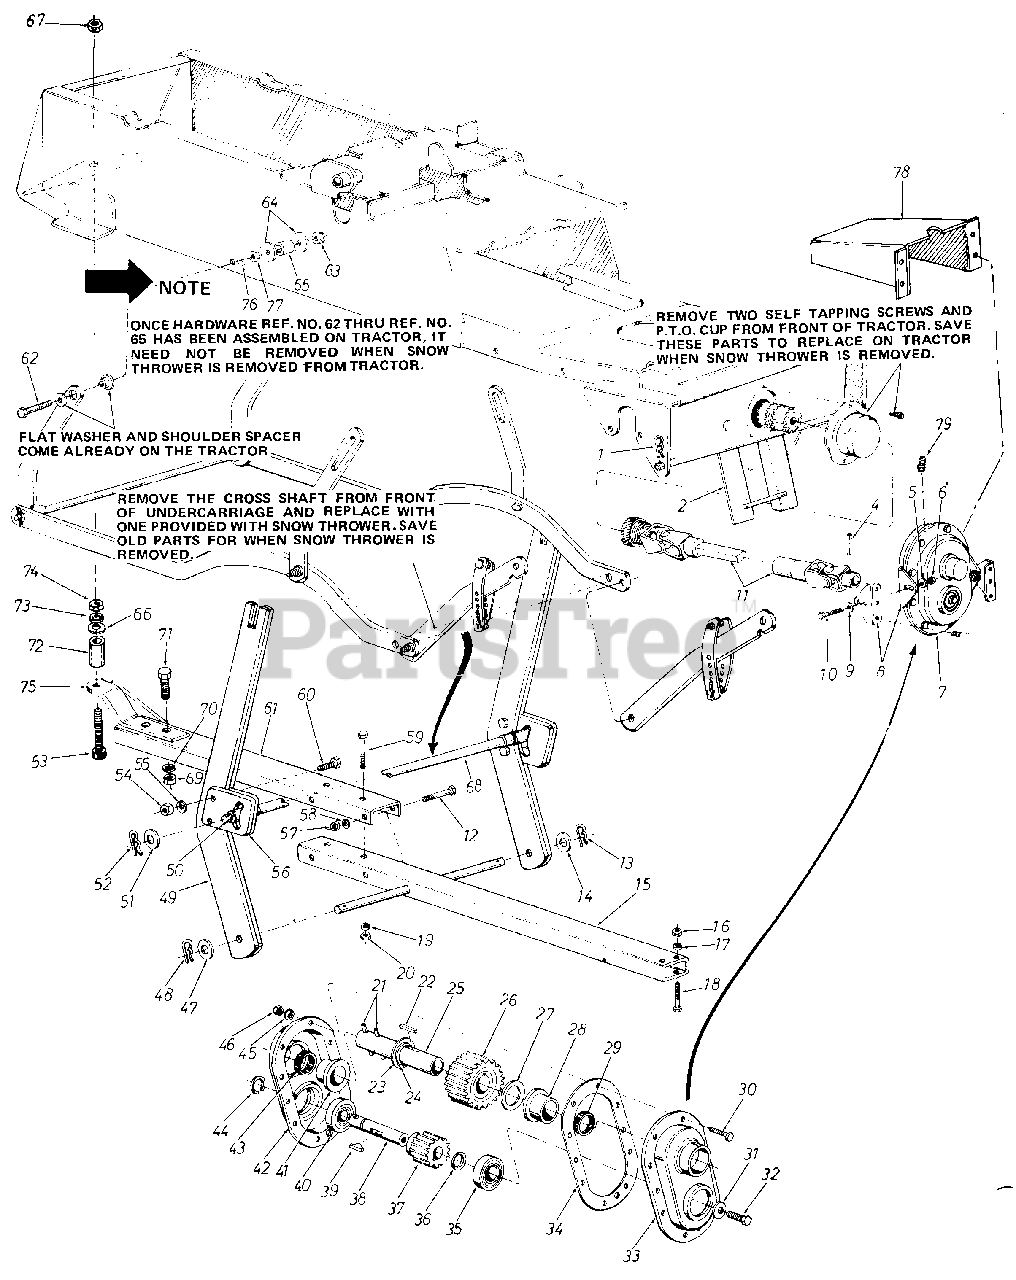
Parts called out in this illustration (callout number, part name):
1	Intern. Cotter Pin 3/4" Dia.
2	Guide Bracket Ass'y.
4	Spring Pin Spirol 1/4" Dia. x Lg.
5	BellevilleWash. .341" I.D. x .88" O.D.
6	Hex Nut 5/16-18 Thd.*
7	Gear Box Ass'y. Comp.
8	Gear Box Support Brk't.
9	Belleville Wash. .341" I.D. x .88" O.D.
10	Hex Scr. 5/ 1 6-1 8 x . 75" Lg.*
11	Universal Drive Shaft Ass'y.
12	Hex Scr.3/8-24 x 4.50" Lg.*
13	Hair Pin Cotter
14	Fl.-Wash. .62" I.D. x 1.12" O.D .
15	Lift Shaft Ass'y.
16	Hex Ins. Jam L.-Nut 3/8-24 Thd.
17	L.-Wash. 3/8" Scr.*
18	Hex Scr. 3/8-24 x 2.75" Lg.*
19	L.-Wash. 3/8" Scr.*
20	Hex lns.JamL.-Nut 3/8-24 Thd.
21	SpringPinSpirol5/16" Dia. x 1.75" Lg.
22	Sq. Key 1/4" x 1/4" x 1.00" Lg.
23	Fl.-Wash. 1.31" I.D. x 2.00" O.D. x .060
24	Snap Ring for 1.25" Dia. Shaft
25	Gear Shaft
26	28 Teeth Spur Gear
27	Fl.-Wash. 1.31" I.D. x 2.00 O.D. x .060
28	Flange Bearing 1.25" I.D. x 1.75" O.D.
29	Oil Seal 1.25" I.D. x 1.75" O.D. O.D. x .26
30	Hex Scr. 1/4-28 x .88" Lg.
31	Fl.-Wash. .40 I.D. x 1.25" O.D. x . 1 60
32	Hex L.-Scr. 3/8-24 x 1.00" Lg.
33	Complete Gear Housing Half-L.H.
34	Gasket
35	Ball Bearing 1.00" I.D. x 2.00" O.D.
36	Fl.-Wash. 1.03" I.D. x 1.63" x .090
37	15 Teeth Spur Gear
39	Woodruff Key 1/4" x 3/4" D ia.
40	Ball Bearing 1.00" I.D. x 2.00" O.D .
41	Flange Bearing 1.25" I.D. x 1.75" O.D.
42	Complete Gear Housing Half-R.H.
43	OilSeal 1.25" I.D. x 1.75" O.D. x .26
44	Snap Ring for 1.00" Dia. Shaft
45	SpringWash. 1/4" I.D.
46	Hex Nut 1/4-28 Thd.
47	Fl.-Wash. .62" I.D. x 1.12" O.D.
48	Hair Pin Cotter
51	Fl.-Wash. .62" I.D. x 1.12" O.D.
52	Hair Pin Cotter
53	Hex Bolt 5/8-18 x 4.00" Lg.
54	Hex Nut 5/16-18 Thd.*
55	L.-Wash. 5/16" Scr.
58	L.-Wash. 3/8" Scr.*
59	Hex Scr. 3/8-24 x 2.75"
60	Hex Scr. 5/16-18 x 1.00" Lg.*
61	Lift Bracket
62	Hex Scr. 3/8-24 x 2.50"
63	Hex Jam L.-Nut 3/8-24 Thd.
64	Fl.-Wash. ..375 I.D. x 1.00" O.D. x . 1 35"
65	Spacer .275 1. D . x .625 O.D. x .440
66	Fl.-Wash. .66" I.D. x 1.25" O.D. x . l 00
67	Hex Jam L.-Nut 5/8-18 Thd.
68	Cross Shaft Ass'y.
69	Hex Nut 1/2-13 Thd.*
70	L.-Wash. 1/2" Scr.*
71	Hex Scr. 1/2-13 x 1.25"
72	Bushing
73	L.-Wash. 5/8" Scr.*
74	Hex Jam Nut 5/8-18 Thd.
77	Hex Nut 3/8-24 Thd.*
78	Drive Shaft Cover
79	Grease Fitting
